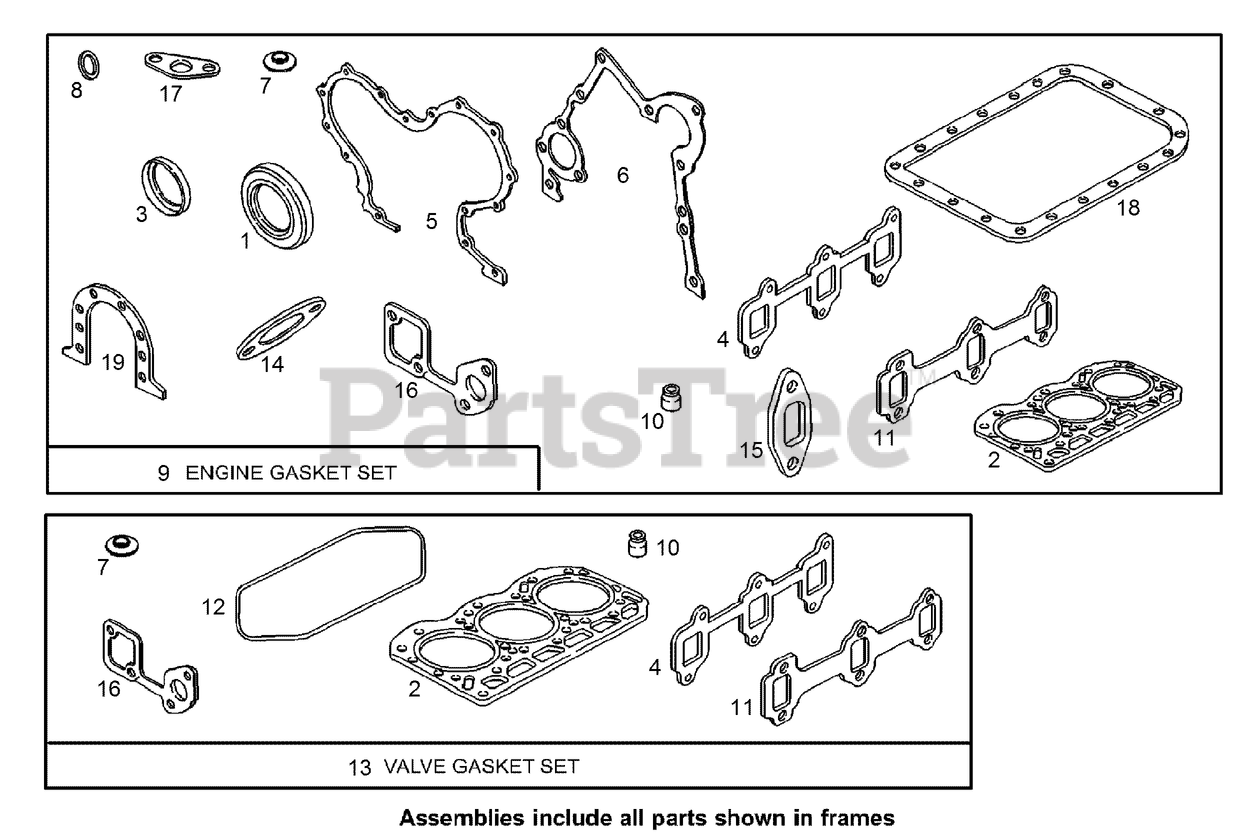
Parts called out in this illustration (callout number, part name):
1	SEAL-OIL
2	GASKET-HEAD, CYLINDER
3	GASKET KIT
4	GASKET-INTAKE
5	GASKET-COVER, GEAR
6	Gasket-Cover, Gear Reduction
7	WASHER-SEAL
8	WASHER-SEAL
9	GASKET SET
10	SEAL-VALVE
11	GASKET-EXHAUST
12	GASKET-COVER, ROCKER
13	VALVE OVERHAUL KIT
14	Gasket-Housing, Outlet
15	GASKET-HOUSING, INLET
16	GASKET-PUMP, WATER
17	GASKET-STRAINER, OIL
18	GASKET-PAN, OIL
19	GASKET-RETAINER
